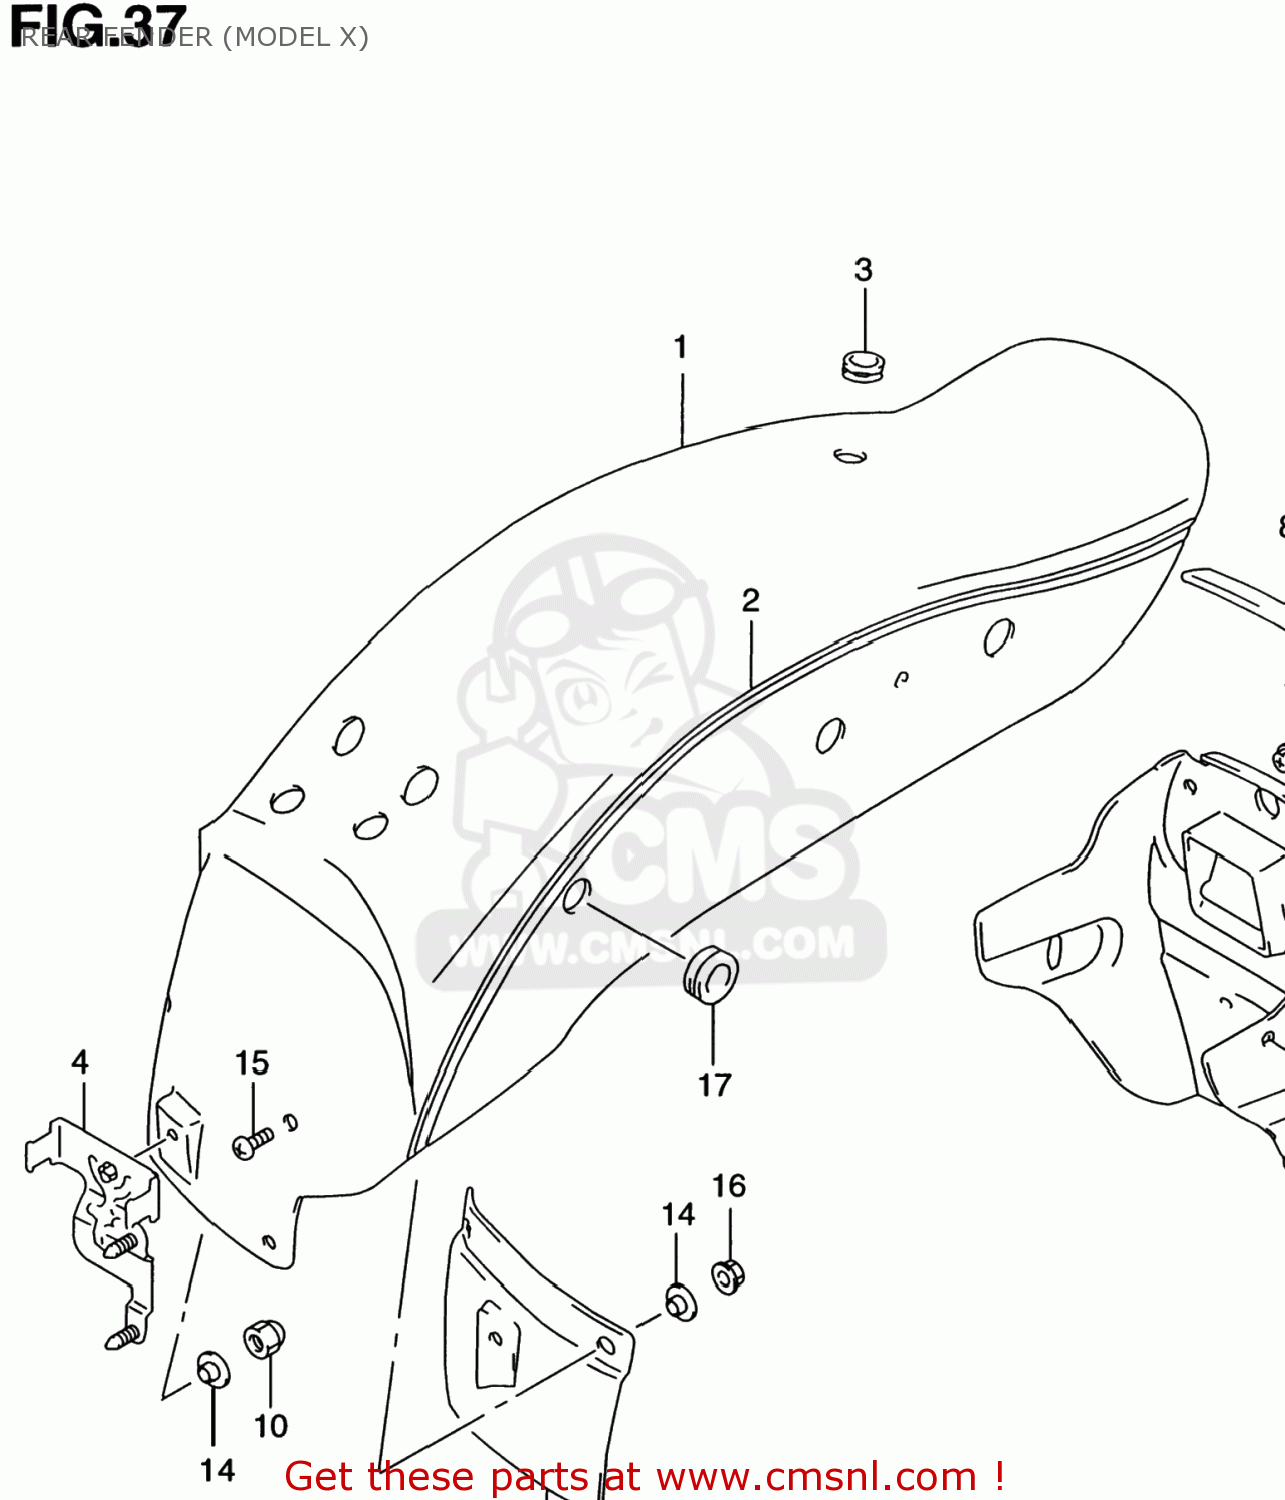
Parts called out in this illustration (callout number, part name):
1	FENDER,RR
2	TAPE SET,RR FENDER
3	CUSHION
4	BRACKET,RR FENDER
5	EXTENSION,RR FENDER
6	SCREW
7	PLATE,FRAME COVER
8	CUSHION,RR FENDER EXTENSION
9	CAP,RR FENDER EXTENSION
10	NUT
11	BOLT
12	WASHER
13	MUDGUARD,RR FENDER
14	WASHER
15	SCREW
16	NUT
17	CUSHION,RR FENDER
